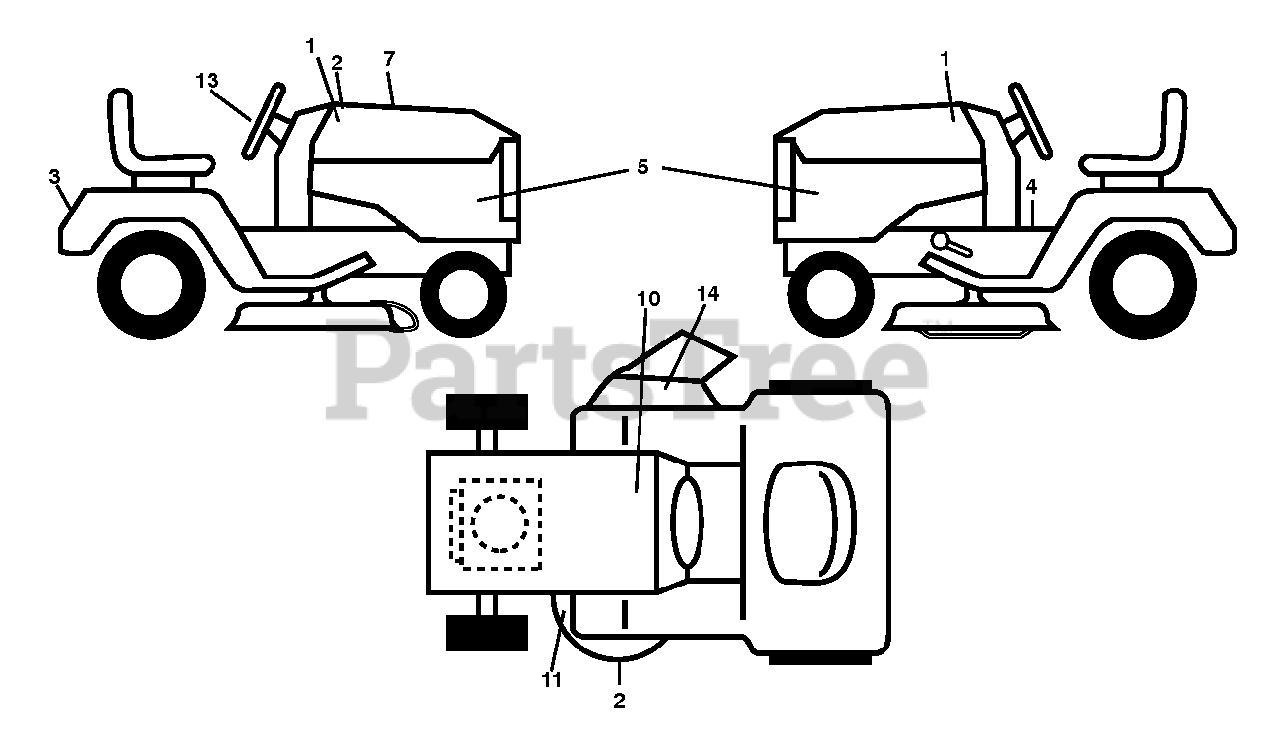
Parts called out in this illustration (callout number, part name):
1	DECAL.FENDER.WARNING.ENGLISH
2	DECAL.PPRO.10YRDECKWAR.POP
3	DECAL.REARFNDR.POULAN PRO.2015
4	DECAL.FENDER.WARNING.ENGLISH
10	DECAL BTRY SYMBOLS
11	DECAL.V-BELT.SCH.42/46"MEC/ELE
13	DECAL.STRWHL.BLK.2014.PPRO
14	DECAL, DECK DEFLECTOR, WARNING
